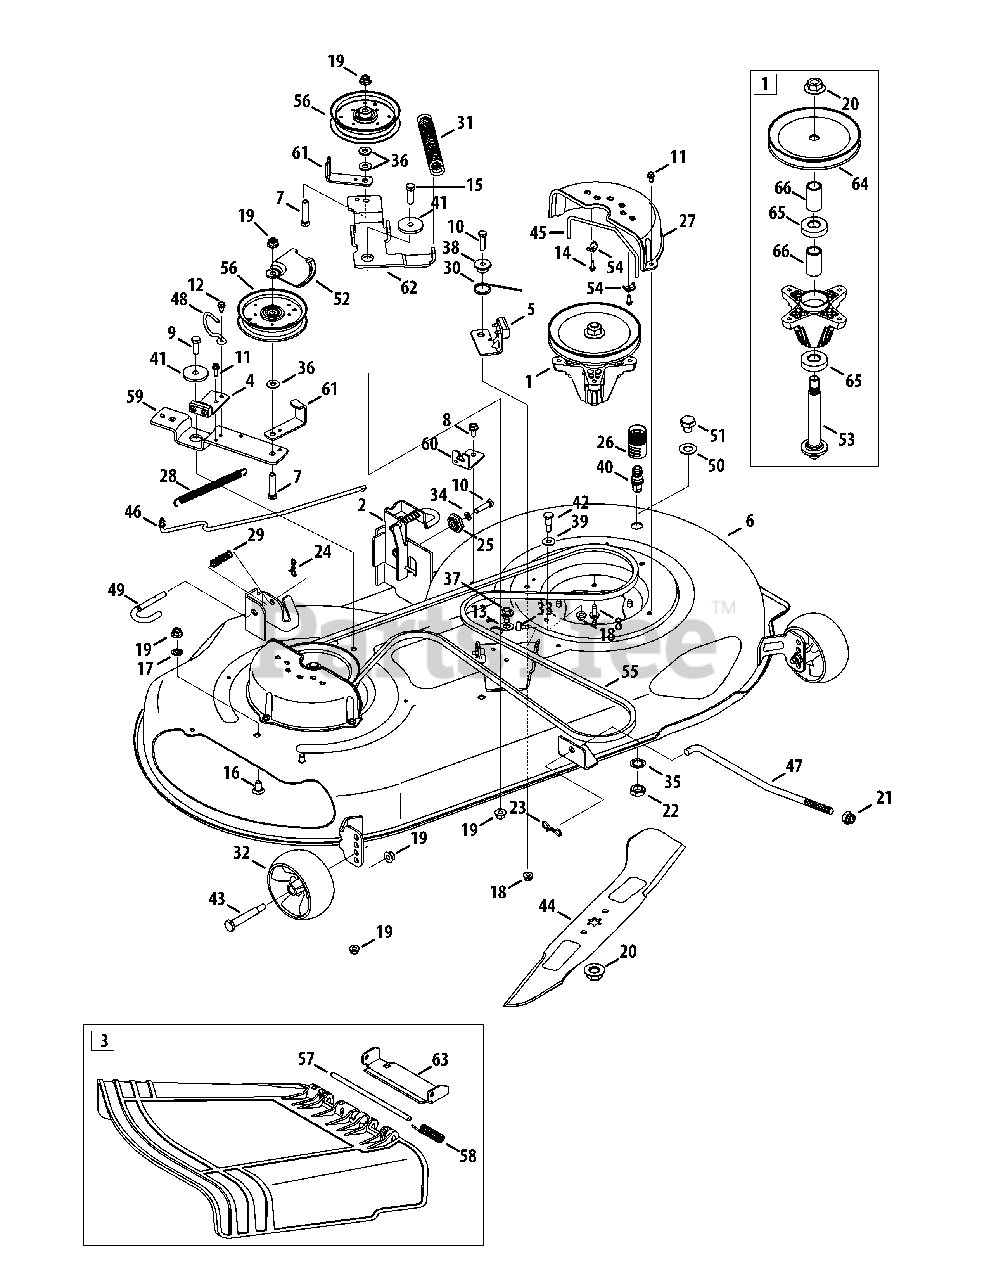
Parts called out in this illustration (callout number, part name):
1	Spindle Assembly, w/Pulley 6.93 Dia
2	Bracket Assembly, Deck Hanger, LH
3	Chute Deflector Assembly
4	Brake Assembly, Deck
5	Brake Assembly, Deck
6	Deck Assembly, 46"
7	Hex Screw, 3/8-16 x 2.00
8	Screw, Self-tapping, 5/16-18, .750
9	Hex Screw, 3/8-16, 1.00, Gr5, Std
10	Hex Screw, 5/16-18, 1.25, Gr5, Std
11	Screw, Self-tapping, 1/4-20, 0.500
12	Screw, Self-tapping, 1/4-20, .750
13	Washer, Flat, .474 x .879 x .064
14	Screw, B, #10-16, 0.625
15	Hex Screw, 3/8-16 x 1.25
16	Bolt, Carriage, 3/8-16, 0.75, Gr1
17	Nut, Push, 3/8
18	Nut, Flange Lock, 5/16-18, Nylon
19	Nut, Flange Lock, 3/8-16, Nylon
20	Nut, Flange, 5/8-18
21	Nut, Lock, 1/2-13
22	Nut, Hex, M16-1.5
23	Bow-Tie Cotter Pin
24	Bow-Tie Cotter Pin, 72
25	Gear, Deck Adjustment
26	Water Nozzle Adapter
27	Belt Cover, Universal
28	Spring, Extension, .62 x 6.12
29	Spring, Compression, .535 x 1.751
30	Spring, Torsion, .992 I.D X 1.17 O.D
31	Spring, Extension, 1.05 X 6.346
32	Wheel, Deck, 5.0 Dia Ball
33	Bumper, .62 Dia X .3
34	Washer, Lock, 5/16, Regular Duty
35	Washer, Lock, 5/8, Int Tooth
36	Washer, Flat, .385 x .870 x .092
37	Shoulder Spacer, .43 x .29, 5/16-18
38	Shoulder Spacer, .50 x .145
39	Washer, Flat, .343 X .880 X .062
40	Deck Water Nozzle
41	Shoulder Spacer, .8840 X .190
42	Shoulder Screw, .437 Dia. X .54
43	Bolt, Shoulder, .496 x 2.50, 3/8-16
44	Blade, Cut, 23.25" 2-In-1
45	Rod, Keeper, Belt
46	Rod, Control, Brake
47	Rod, Lift, Deck
48	Rod, Keeper, Belt
49	Rod, Deck Release
50	Washer, Flat, .64 X 1.24 X .06
51	Plug, Bolt, M16 X 1.5
53	Spindle Shaft, 6.05 LG.
54	Clamp, Casing
55	Belt, V-Typ, A Sec
56	Pulley, Idler, 4.25"Dia
58	Torsion Spring
59	Bracket, Idler, Pivot
60	Bracket, Cable, Deck Engagement
61	Bracket, Guard, Belt, 4.25 Pulley
62	Bracket, Idler, Lh
63	Chute Bracket
64	Deck Pulley, 6.93 DIA
65	Ball Bearing, .787ID X 1.85 ODX.551
66	Spacer, .792 X 1.060 X 1.860 LG
